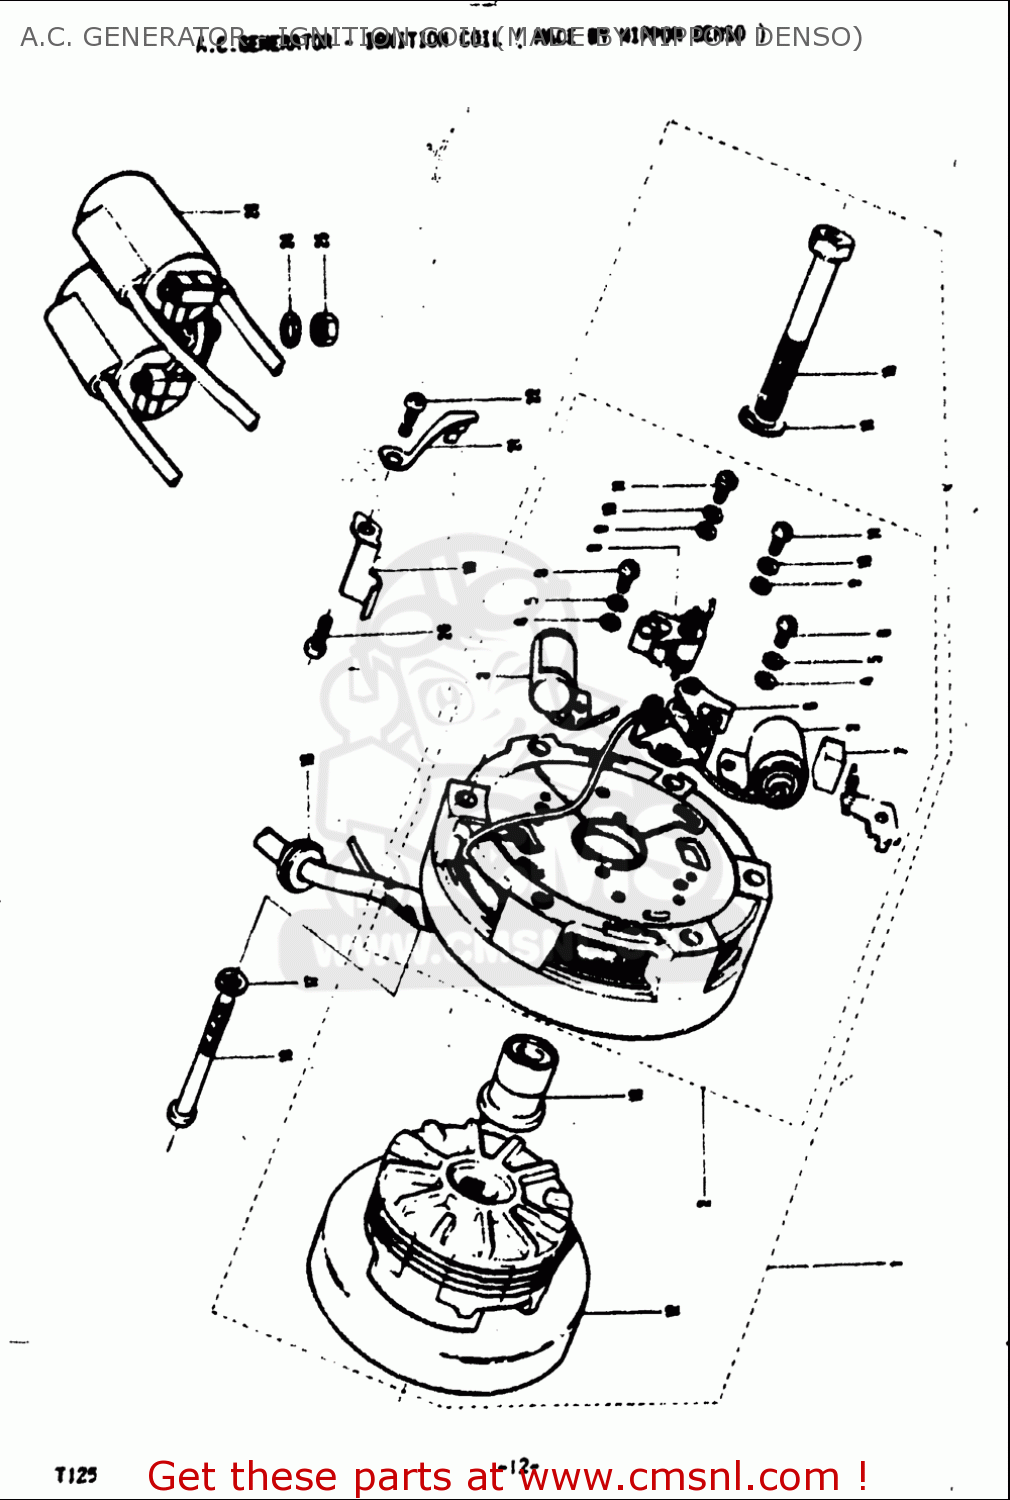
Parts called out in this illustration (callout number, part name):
4	WASHER
5	WASHER,LOCK
6	SCREW(4X10)
8	POINT ASSY,CONTACT
9	WASHER
10	WASHER,LOCK
11	.SCREW
14	WASHER,LOCK
17	WASHER,LOCK
18	SCREW
24	WASHER,LOCK
25	NUT
